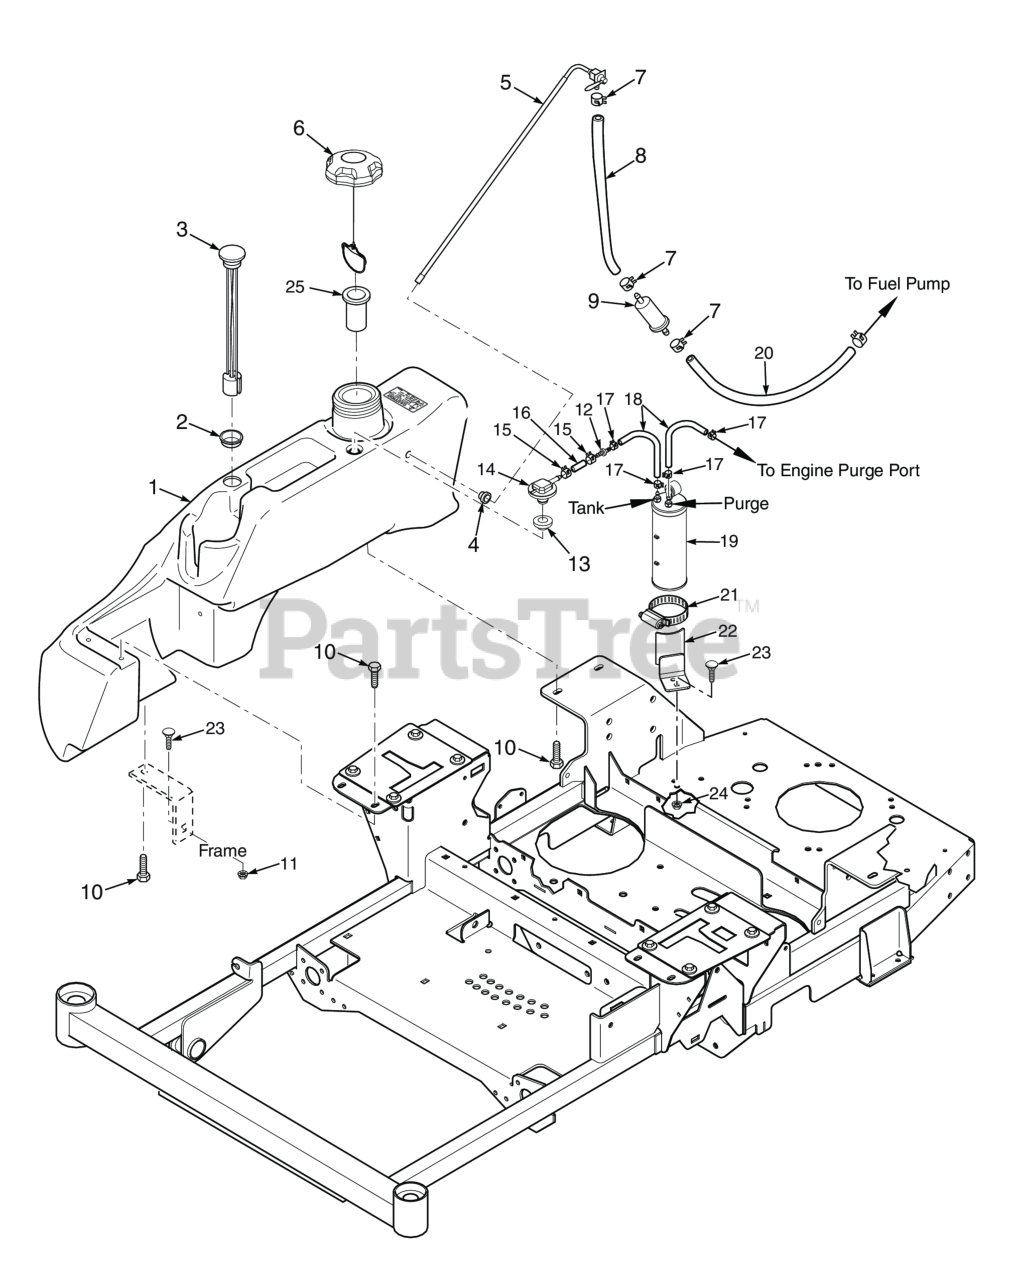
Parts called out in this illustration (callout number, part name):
1	Fuel Tank Assembly - SPZ (Includes 2,3,4,5,13,14)
2	Grommet, Fuel Gauge
3	Fuel Gauge Assembly
4	Bushing, 0.56" Dia. Viton
5	Fuel Tube Assembly
6	Fuel Cap w/ Tether (E.P.A.)
7	Clamp, Fuel Hose 1/4" Hose I.D.
8	Fuel Hose, 1/4" I.D. Non-Perm (791DFI Fuel Return) - Order by Inch
9	Fuel Filter
10	CAP SCREW, 5/16-18 X 1/2" SERRATED FLANGE HEX
11	Nut, Flange Head Elastic Stop 5/16-18
12	Mender, 1/4 x 3/16 w/0.02 Hole
13	Grommet, Viton,
14	Remote Vent, No Valve
15	CLAMP, FUEL HOSE(KAWASAKI ONLY)
16	Hose, 1/4" Vapor Recovery (order by inch)
17	Clamp, Vapor Recovery Hose 3/16"
18	Hose, Vapor Recovery 3/16" (order by inch)
19	Carbon Canister - SVR-52V / SVR-61V
20	Fuel Hose
21	Clamp, 3-1/2" Max. Dia.
22	Bracket Weldment, Kawasaki Models
23	Bolt, 5/16-18 x .75 RHSN Carriage
24	Nut, Serrated Flange 5/16-18 (Right Front Engine Mounting, Briggs and Kohler Only)
25	Tube, Fuel Tank Insert - 4"
